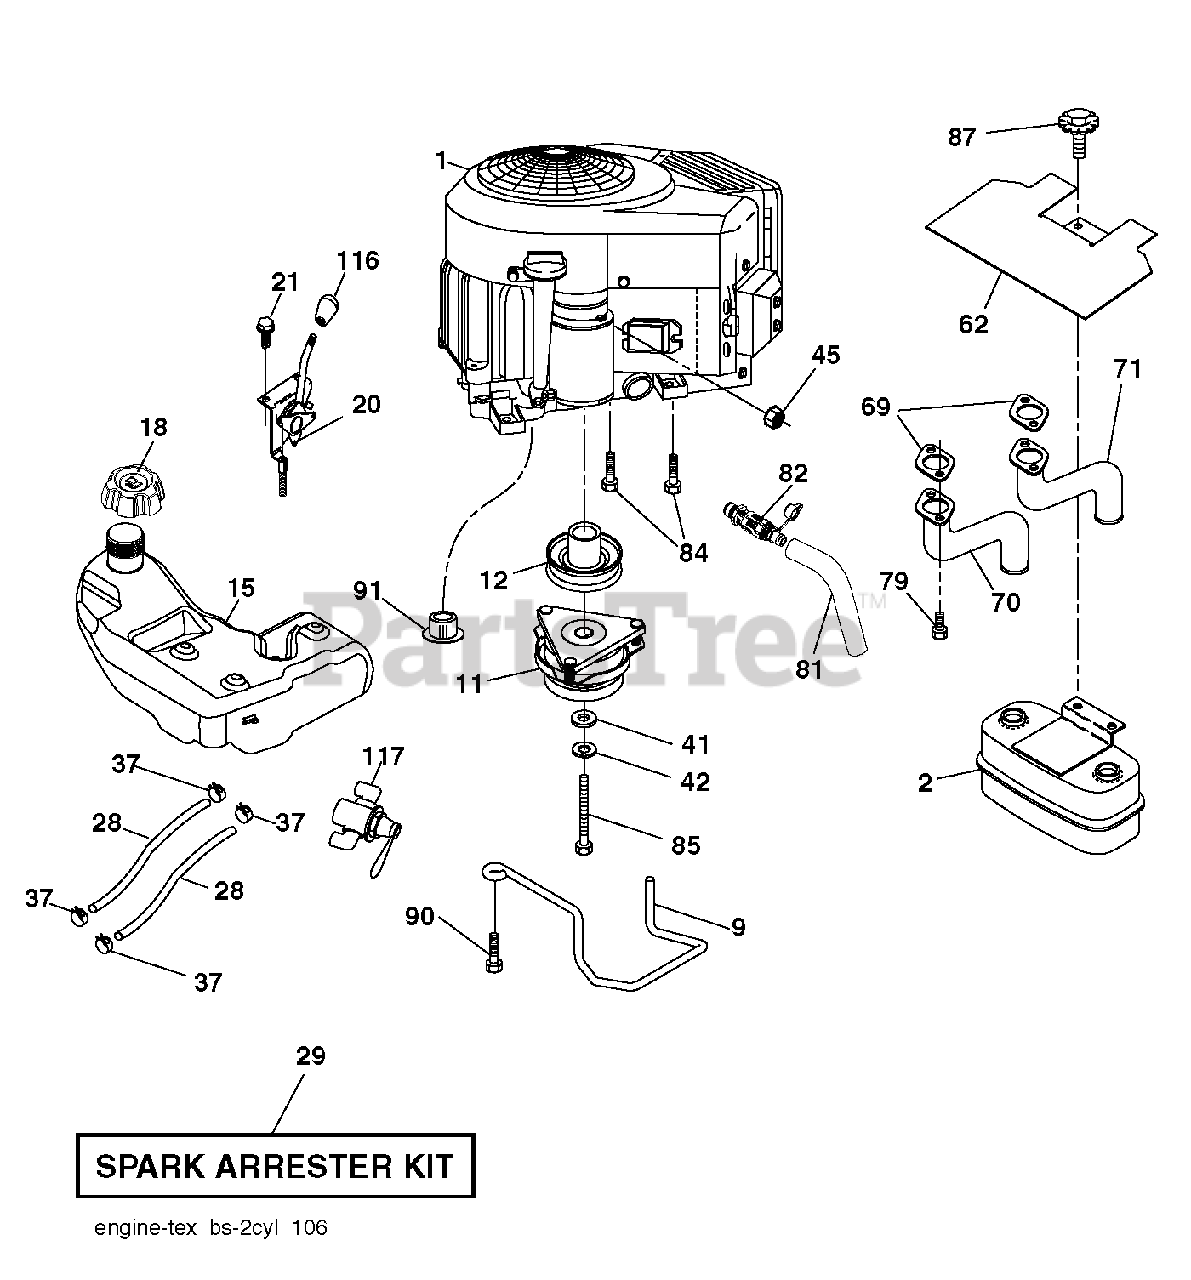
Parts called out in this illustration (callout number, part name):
2	MUFFLER.ASM.TWN.EXTNDED.DFLCTR
9	KEEPER BELT ENGINE
11	CLUTCH.ELECTRIC.LT.48"*
12	PULLEY.ENGINE.TUFFTORQ
18	CAP.ASSY.FUEL.3".N-EPA.GRY.498
20	CONTROL.THROTTLE/CHOKE.PRO.45
21	SCREW.#10 X 0.750.BOS
28	REPL BY 532 00 85-43
29	KIT.SPARK ARRESTOR 794945 B&S
37	HOSE CLAMP
42	LOCKWASHER
45	NUT
62	SHIELD.HEAT.MUFFLER
69	GASKET.MUFFLER
70	EXHAUST.TUBE.LH.BS/TWIN
71	EXHAUST.TUBE.RH.B&S.TWIN.INTEK
79	SCREW.SOCKET.HEAD.5/16-18
81	TUBE, DRAIN OIL ASM.
82	VALUE.OIL.DRAIN
84	SCREW.3/8-16
85	BOLT HEX 7/16-20X4-1/4"
87	Bolt, 5/16-18 X 1-3/4
90	SCREW 3/8-16X1
91	BUSHING.1.375OD
116	KNOB - SHIFT
117	VALVE FUEL RESERVE
